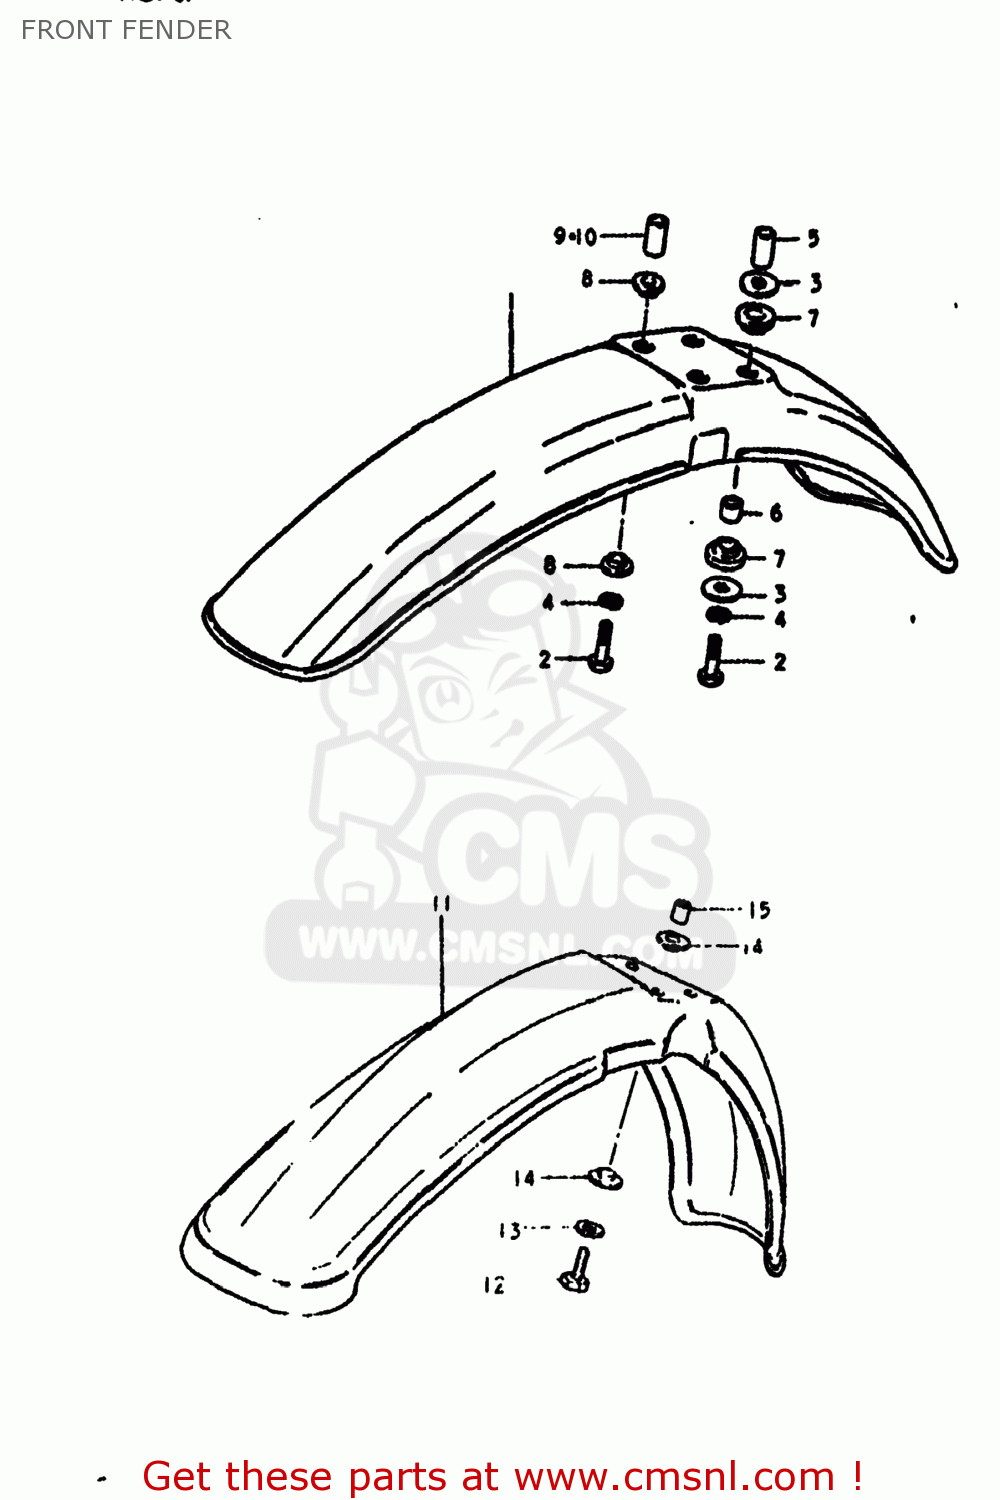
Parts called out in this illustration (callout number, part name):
1	FENDER,FRONT
2	BOLT
3	WASHER (6.5X20X1.2)
4	LOCK WASHER
5	SPACER
6	SPACER (6.8X10X10)
7	CUSHION
8	SPACER
9	SPACER
10	SPACER (6.8X10X20)
11	FENDER,FRONT
12	BOLT
13	LOCK WASHER
14	SPACER
15	SPACER
